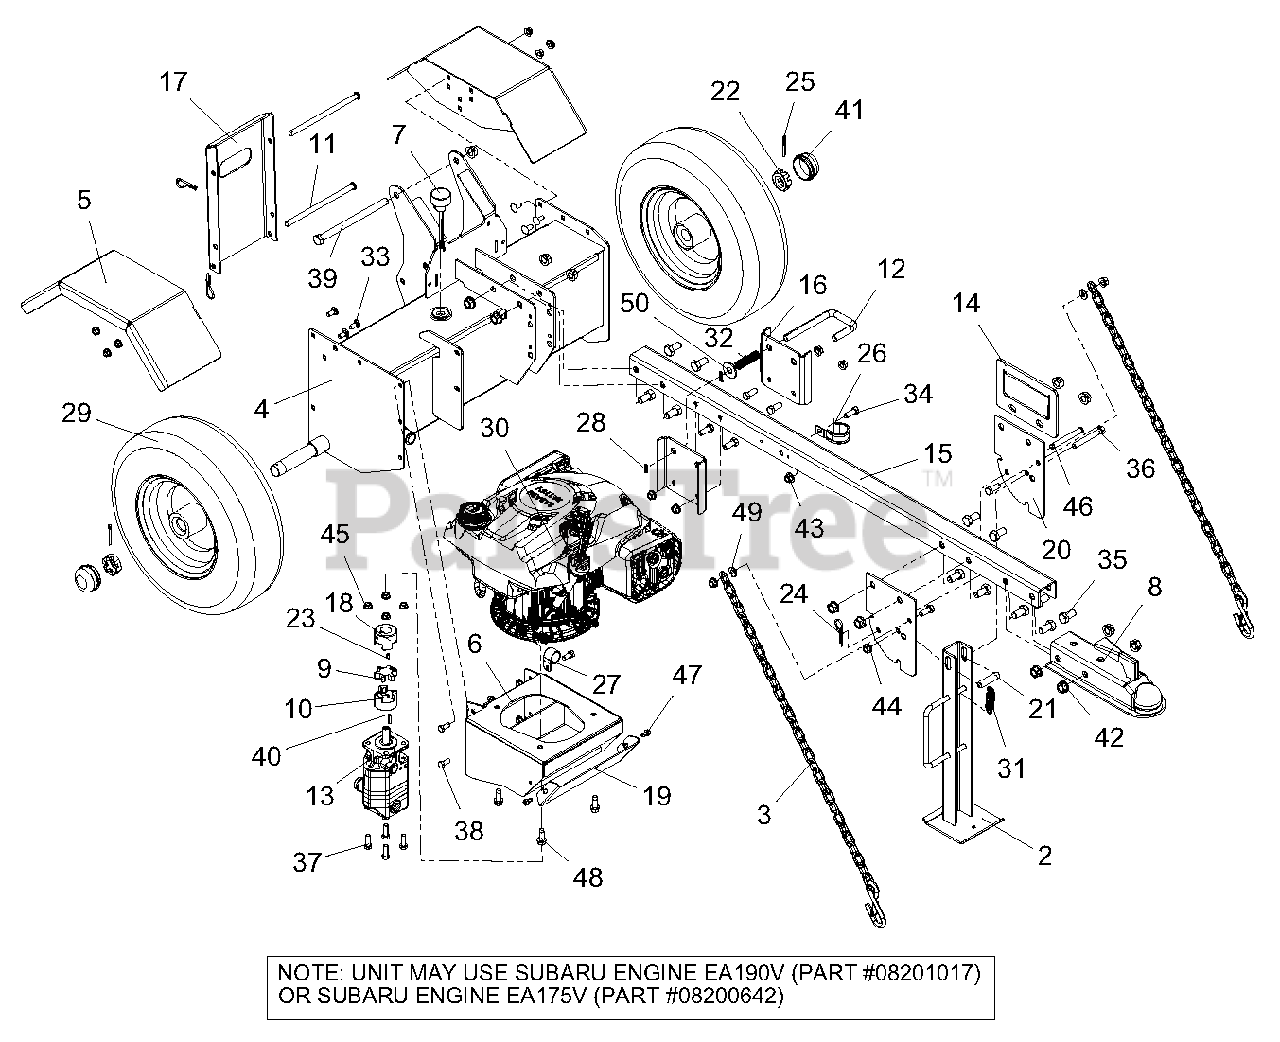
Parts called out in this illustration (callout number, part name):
2	WLDMT, JACK STAND
4	WLDMT, CHASSIS-SPLITTER-(SMALL)-RED
5	WLDMT, FENDER
6	WLDMT, ENGINE /PUMP MOUNT
7	BREATHER, DIPSTICK
8	HITCH, BALL - 2"
9	SPIDER, URETHANE
10	HUB, DRIVE COUPLING 1/2"
11	PIN, CLEVIS .375 x 7.25
12	LOCK, BEAM
13	PUMP, SPLITTER - 11 GPM
14	HANDLE, SPLITTER DRAW BAR-BLACK
15	DRAWBAR, (CHANNEL)
16	GUIDE, LOCK DOWN
17	SUPPORT, REAR LEG
18	HUB, DRIVE COUPLING 7/8
19	COVER, COUPLING
20	MOUNT, SPRG LOADED JACK
21	SPCR, WHEEL .385 x .500 x 2.00
22	NUT, SL 1.0-14
23	KEY, WDRF .125 x .50 x .20 (HRDEND)
24	HAIR, PIN #7 CLIP .094 x 2.31 YWZ
25	PIN, CTR .15 x 1.50 YWZC
26	CLAMP, CUSHIONED STEEL, 1.25
27	CLAMP, CUSHIONED STEEL REV
28	CLIP, SPRING
29	WHEEL, SPLITTER 8 x 3.75 W/4.125 GREY
30	ENGINE, SABARU EA175V SS 4.5HP
31	SPRG, EXTENSION
32	SPRG, COMPRESSION .058 x .65 x 2.13
33	BLT-RDHDSQNK .31-18 x .75 G5 YWZC
34	BLT-HEX .38-16 x 1.00 GR5 YWZC
35	BLT-HEX .50-13 x 1.00 GR5 YWZC
36	BLT-HEX .38-16 x 3.00 GR5 YWZC
37	BLT-HEX .31-18 x 1.00 GR5 YWZC
38	BLT-HEX .31-18 x .75 GR5 YWZC
39	BLT-HEX .50-13 x 7.50 GR5 YWZC
40	KEY-SQ .188 x .188 x .750
41	CAP, DUST
42	NUT-LK-CTR-FLG .50-13 YWZC
43	NUT-LK-NYL-FLG .38-16 YWZC
44	NUT, LK-TOP-FLG .38-16 YWZC
45	NUT, LK-TOP-FLG .312-18 YWZC
46	PIN, CLEV .375 x 3.25 YWZC
47	SCR-TAP .25-20 x .50 HWH TR YWZ
48	SCR-TAP .38-16 x 1.00 HWH TR YZ
49	WSHR-FL-STL .406 x .812 x .065 YWZ
50	WSHR-FL-STL .563 x 1.38 x .109YWZC
